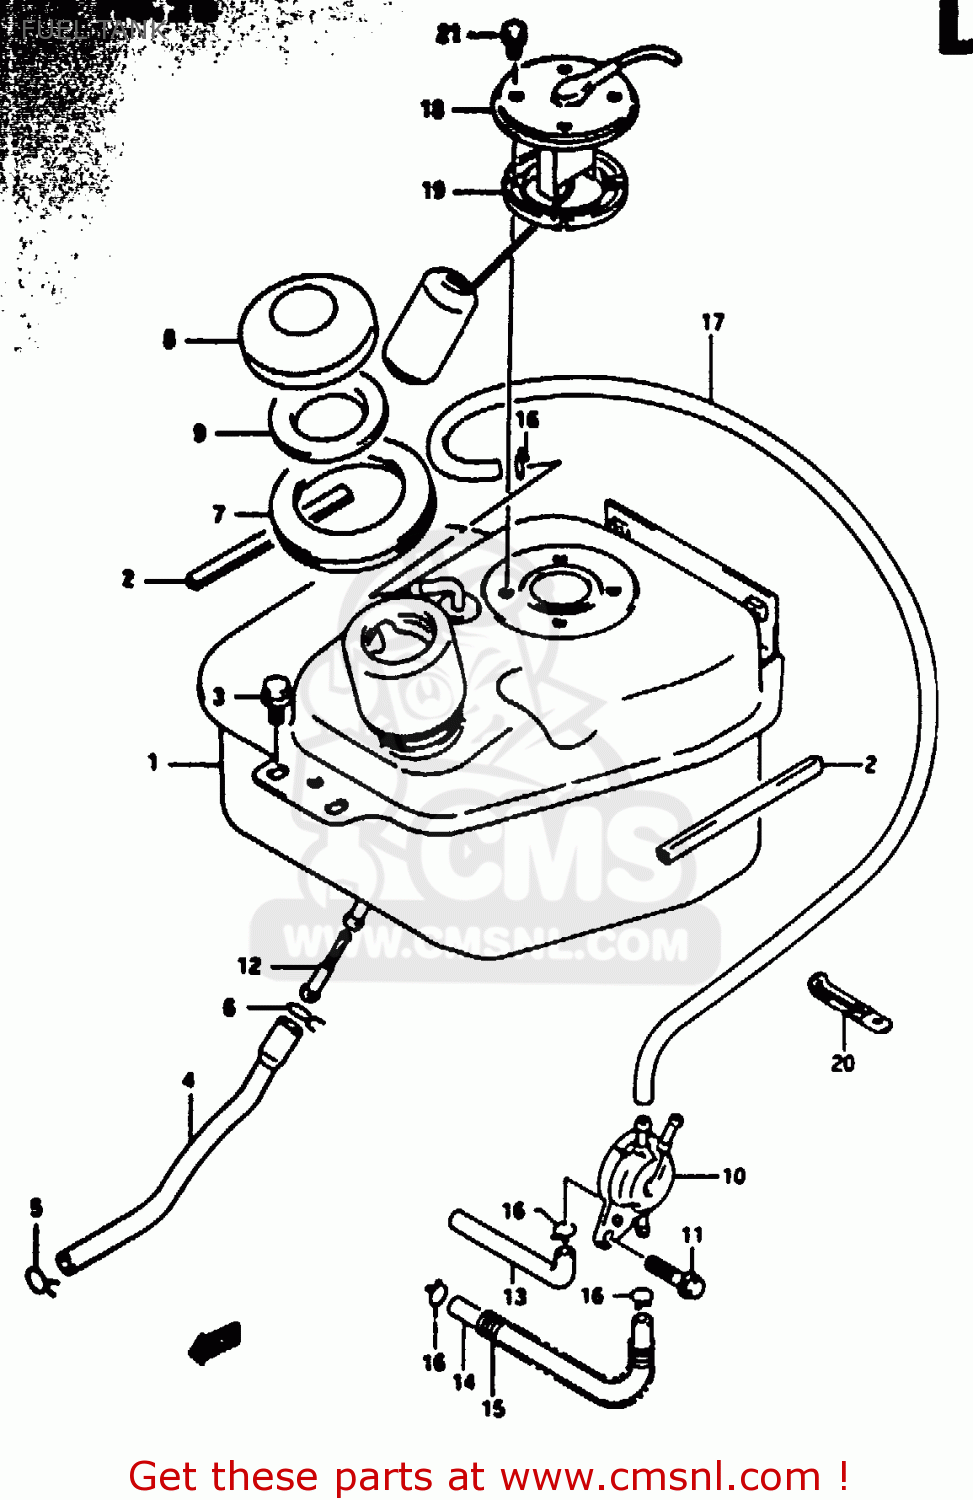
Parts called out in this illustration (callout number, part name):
1	TANK COMP,FUEL
2	SEAL
3	BOLT
4	HOSE,FUEL TANK INLET
5	CLIP
6	CLIP
7	GROMMET,FUEL TANK INLET
8	CAP,FUEL TANK
9	GASKET (NAS)
10	COCK ASSY,FUEL
11	BOLT
12	FILTER,FUEL
13	HOSE(5X8.2X600)
14	HOSE(5X8.2X600)
15	SPRING
16	CLIP
17	HOSE,AIR VENT
18	GAUGE ASSY,FUEL LEVEL SENDER
19	PACKING (NAS)
20	CLAMP(L:45)
21	BOLT
